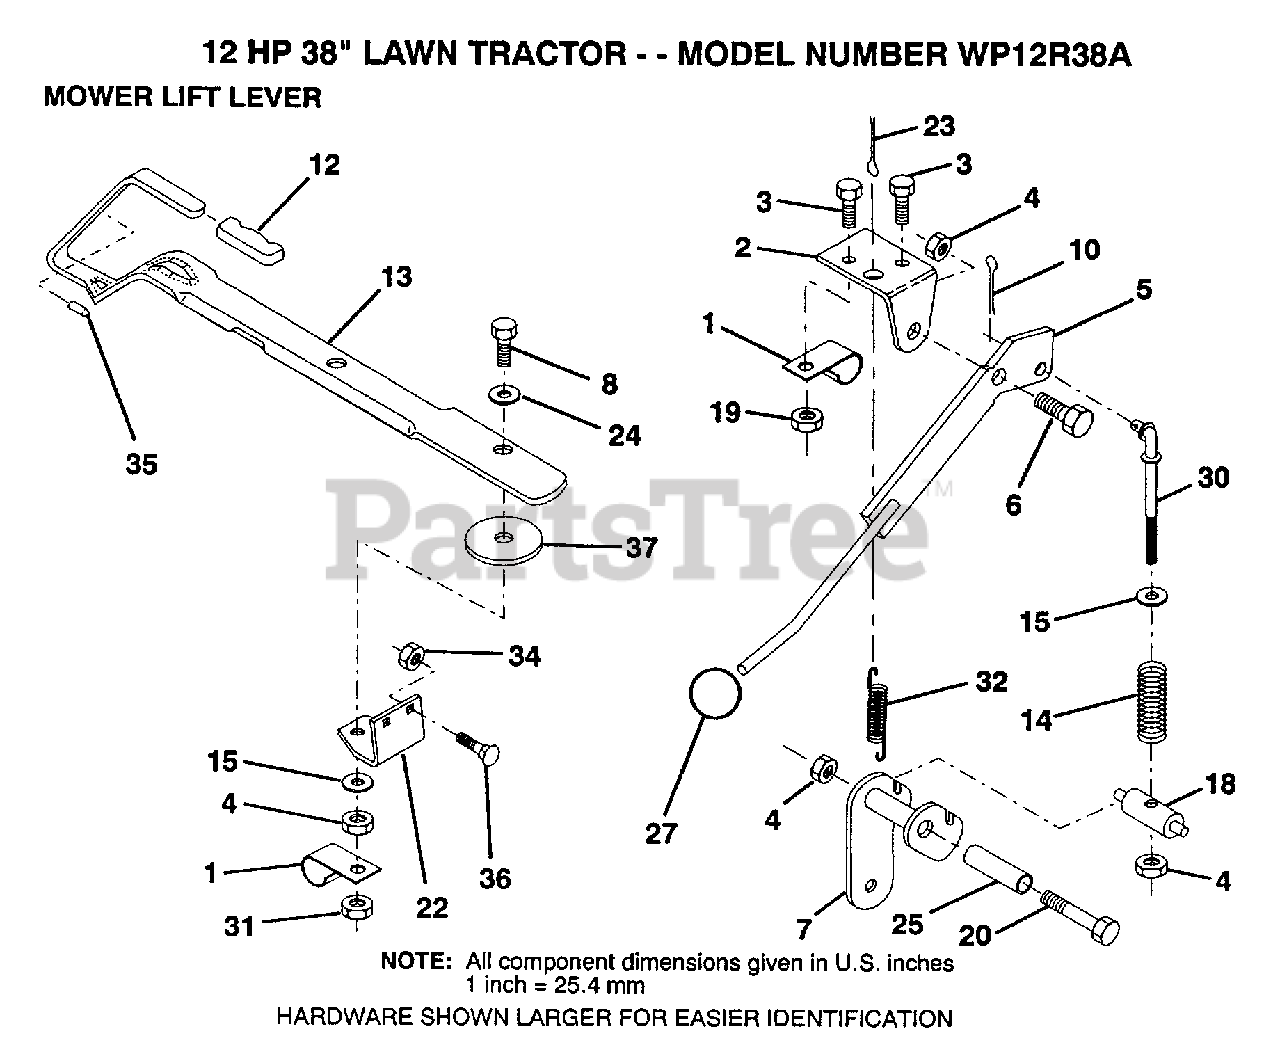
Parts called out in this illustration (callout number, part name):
1	"CLIP,INSULATOR"
2	BRKT CLUTCH
3	BOLT
5	CLUTCH LEVER AS
6	"BOLT, SHOULDER LT"
7	MWR CLUT ARM ASM
8	BOLT
10	COTTER PIN
12	LIFT LEVER HANDLE
14	COMP CLUTCH SPRNG
15	WASHER HYT
18	TRUNNION
20	BOLT
22	LIFT LEVER BRKT
24	WASHER
25	TUBE SPACER
27	KNOB T(3/8 HOLE)
30	ROD TENSION CLUTC
31	LOCKNUT
32	SPRING EXT
35	VINYL CAP RED
36	BOLT
37	WASHER T
